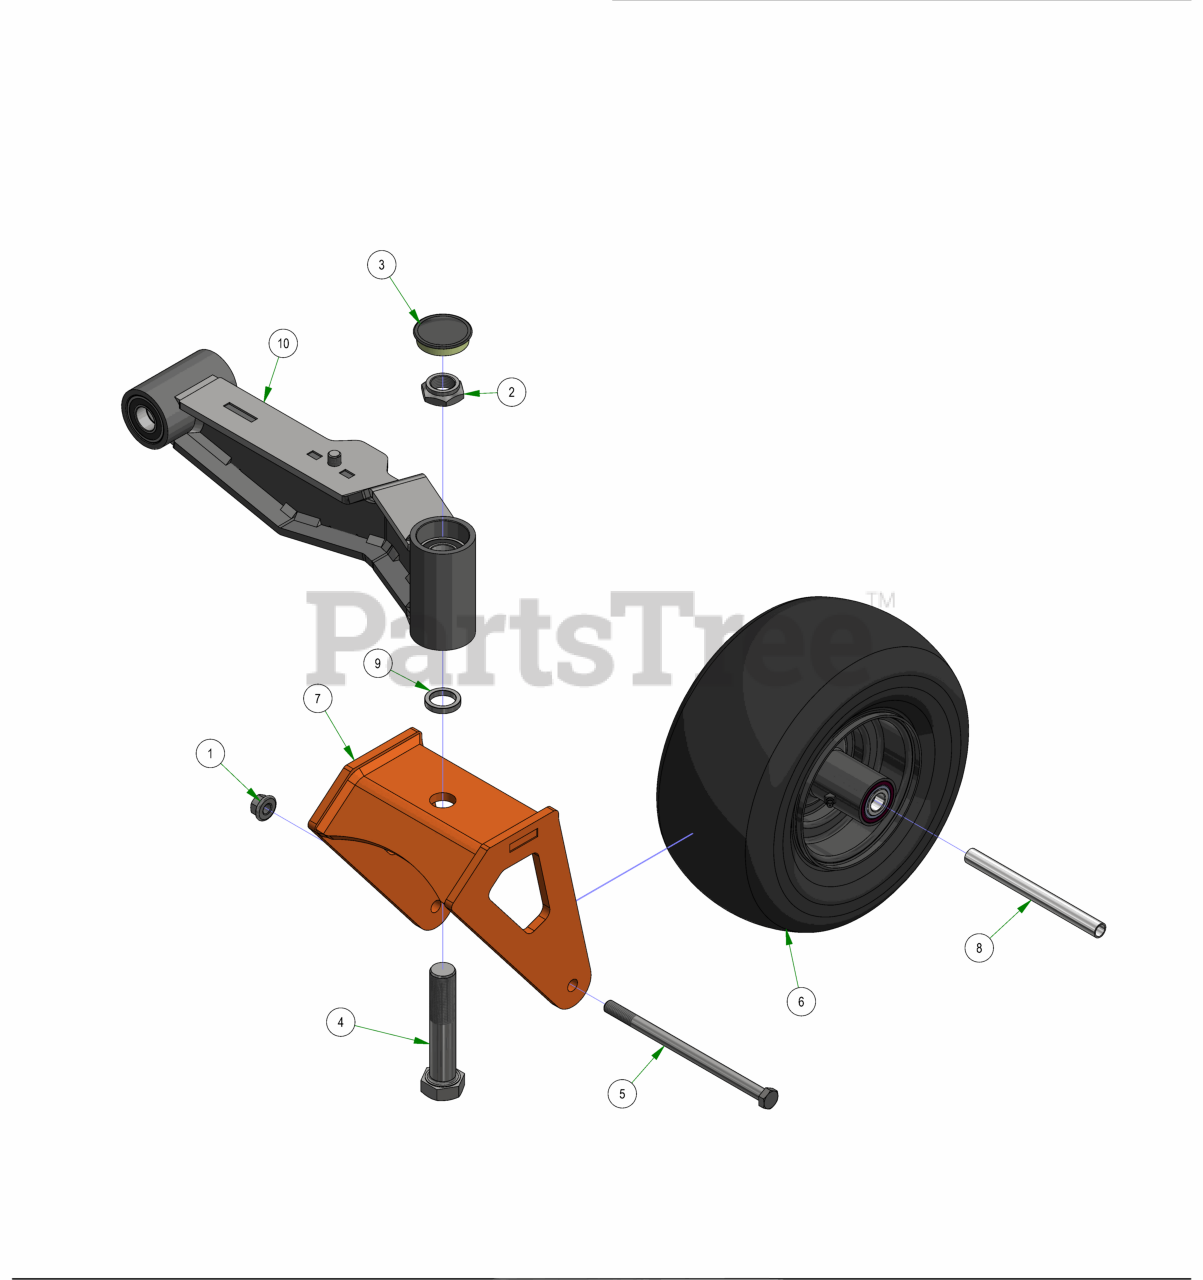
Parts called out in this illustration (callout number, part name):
1	1/2-13 NYLON INSERT FLANGE LOCKNUT ZINC
2	1"-14 NYLON INSERT JAM LOCKNUT ZINC
3	2017 Bearing Cover
4	1"-14 X 5 HEX CAP SCREW (GR.8) ZINC YELLOW
5	1/2-13 X 8-1/2 HEX CAP SCREW (GR.5) ZINC
6	13x6.50-6 Black No Flat Assembly
7	2019 Stand-on Front Fork Weldment
8	Front Wheel Spanner
9	1.02 ID X 1.38 OD X .250 THK SPACER ZINC
10	2022 Maverick LH Front Suspension Arm Assy (42'')
